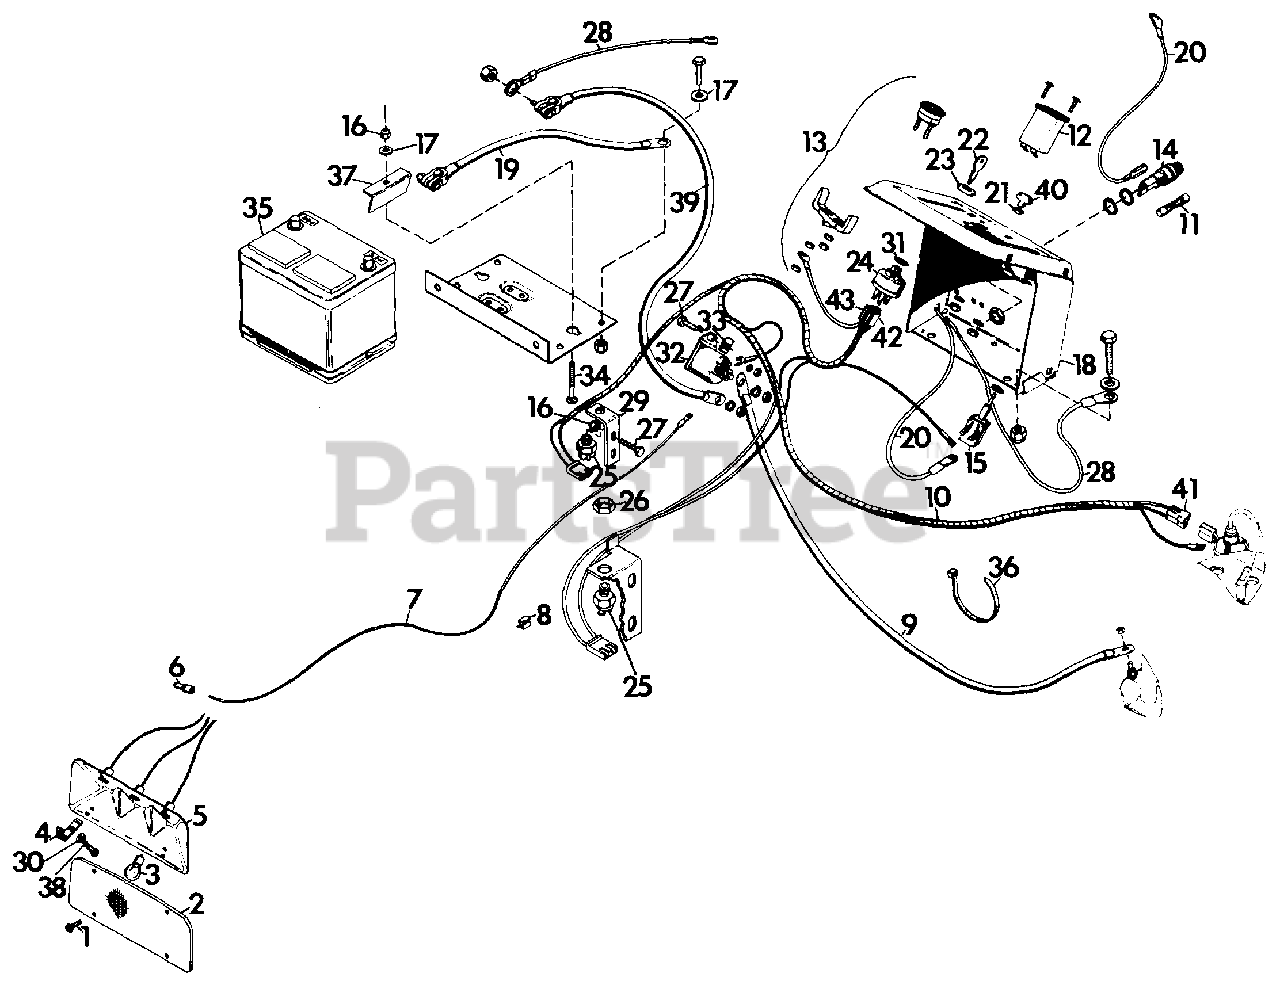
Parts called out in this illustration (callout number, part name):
1	SCREW, MACH. 10-24X.50 PHD
2	PANEL, FRONT LIGHT
3	LAMP, NO. 1073
4	CLIP, LIGHT MTG.
5	ASSEMBLY, LAMP REFLECTOR
6	NUT, WIRE
7	WIRE, HEADLIGHT
8	CLIP, WIRE
9	CABLE, STARTER
10	HARNESS, WIRING KOHLER TWIN
11	FUSE, 30 AMP AGC-30
12	HOURMETER
13	GAUGE, AMMETER
14	FUSE, PANEL
15	SWITCH, LIGHT
16	NUT, LOCK 1/4-20
17	WASHER, FLAT .281X.625X.065
18	PANEL, INSTRUMENT W/AMMETER & HOURMETER
19	CABLE, NEGATIVE BATTERY
20	WIRE, HOURMETER
21	NUT, SPECIAL LIGHT SWITCH
22	KEY, IGNITION SWITCH
23	NUT, JAM 9/16-24
24	SWITCH, IGNITION
25	SWITCH, INTERLOCK
26	NUT, STAMPED 9/16-18
27	BOLT, HEX 1/4-20X.625
28	WIRE, INSTRUMENT PANEL
29	BRACKET, SWITCH
30	WASHER, FLAT .188X.562X.049
31	WASHER, LOCK 9/16 INT. TOOTH
32	SWITCH, MAGNETIC
33	NUT, SPEED 1/4-20
34	BOLT, 1/4-20X1.75 RD HD SQ NK
35	BATTERY, 12 VOLT
36	TIE, CABLE
37	CLAMP
38	SCREW, MACH. 10-24X.75 PHD
39	CABLE, BATTERY TO MAGNETIC SWITCH
40	KNOB, LIGHT SWITCH
41	CONNECTOR
42	CONNECTOR
43	TERMINAL
NS	WASHER, LOCK 1/4 EXT. TOOTH TYPE A
NS	BOOT, BATTERY CABLE
